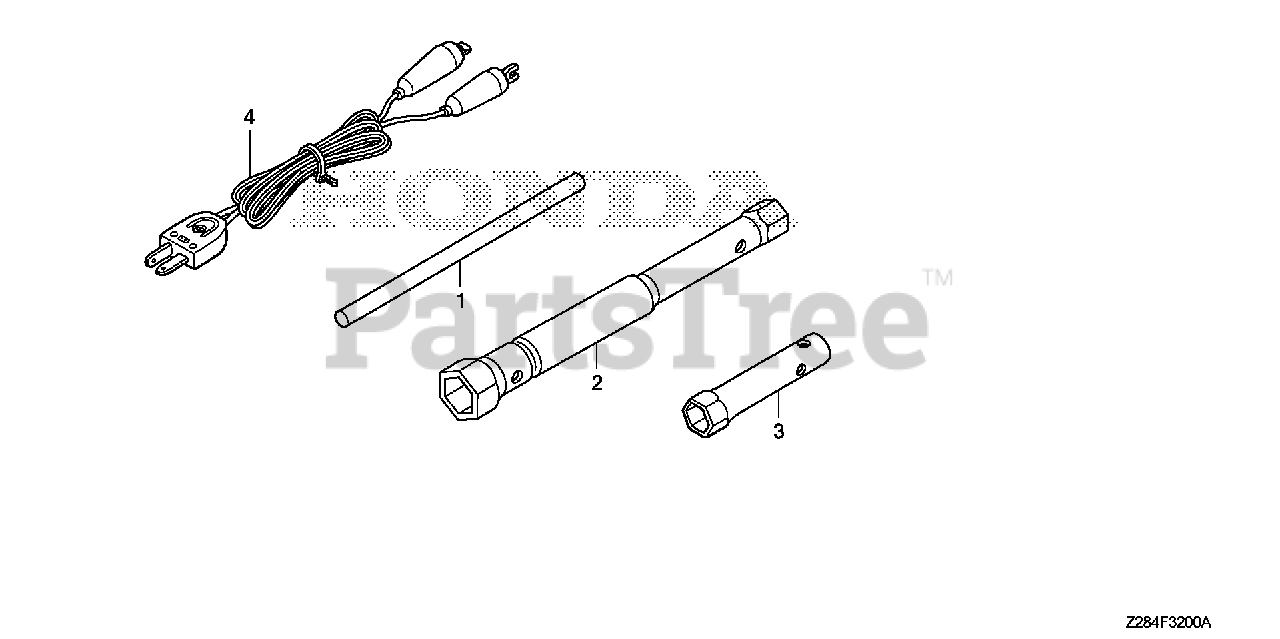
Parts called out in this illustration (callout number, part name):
1	BAR, PLUG WRENCH
2	WRENCH, BOX (P21X10)
3	WRENCH, BOX (10MM)
4	WIRE ASSY., CHARGE (2M)
